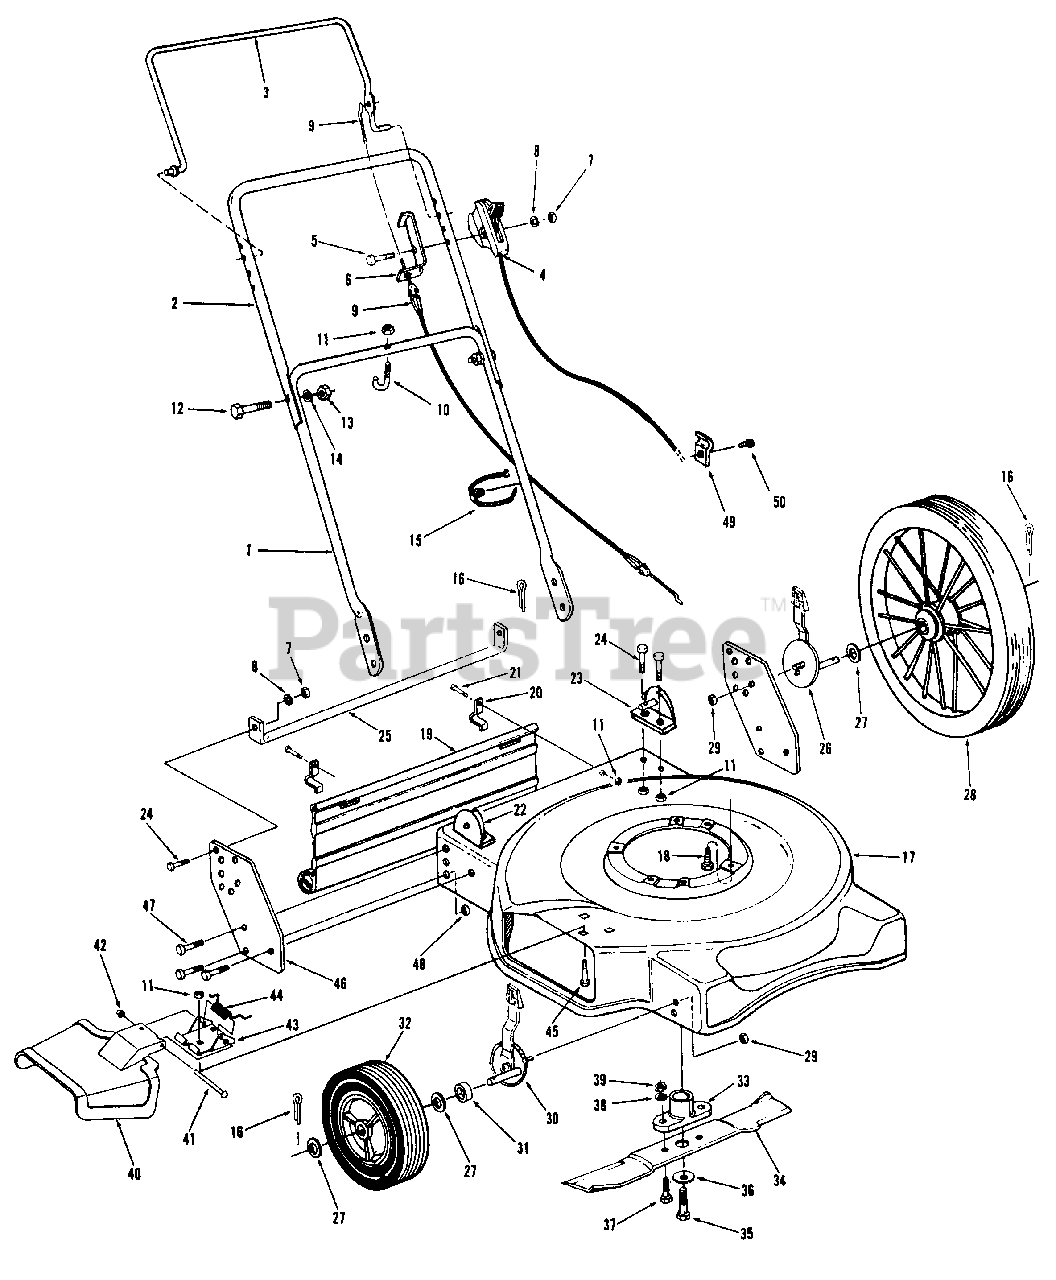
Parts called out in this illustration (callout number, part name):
1	Lower Handle
2	Upper Handle
3	Engine Control Lever
4	Throttle Control
5	Hex Bolt 1/4-20 x 2.00" Lg.
6	Cable Mounting Bracket
7	Hex Nut 1/4-20 Thd
8	L-Wash. 1/4" I.D.
9	Control Cable - 36"
10	Rope Guide
11	Hex L-Nut 1/4-20 Thd
12	Hex Bolt 5/16-18 x 1.50 Lg.
13	Hex Nut 5/16-18 Thd
14	L-Wash. 5/16 I.D.
15	CableTie
16	Cotter Pin 1/8 x 3/4" Lg.
17	22"Deck Ass'y
18	Engine Mtg. Bolt
19	Rear Flap
20	Hinge Bracket
21	Hex Bolt 1/4-20 x .62" Lg.
22	Handle Bracket - RH
23	Handle Bracket - LH
24	Hex Bolt 1/4-20 x .62" Lg.
25	Stabilizer Bar
26	Adjustor Ass'y - Left Rear
27	Fl-Wash. 1/2" I.D.
28	16" Steel Spoke Wheel
29	Hex L-Nut 3/8-16 Thd
30	Adjustor Ass'y - Right Front
31	Wheel Spacer
32	8" Wheel Ass'y
33	Blade Adaptor Kit
34	22" Blade
35	Blade Bolt
36	Bell-Wash. .460 I.D.
37	Hex Bolt 3/8-24 x 1.00 Lg.
38	L-Wash. 3/8" I.D.
39	Hex Nul 3/8-24 Thd.
40	Chute Deflector
42	Retainer
43	Adaptor Plate
45	Carriage Bolt 1/4-20 x .50 Lg.
46	Bracket
47	Hex Bolt 3/8-16 x 3/4" Lg.
48	Hex L-Nut 3/8-16 Thd.
49	Casing Clamp
50	Scr. - Casing Clamp
